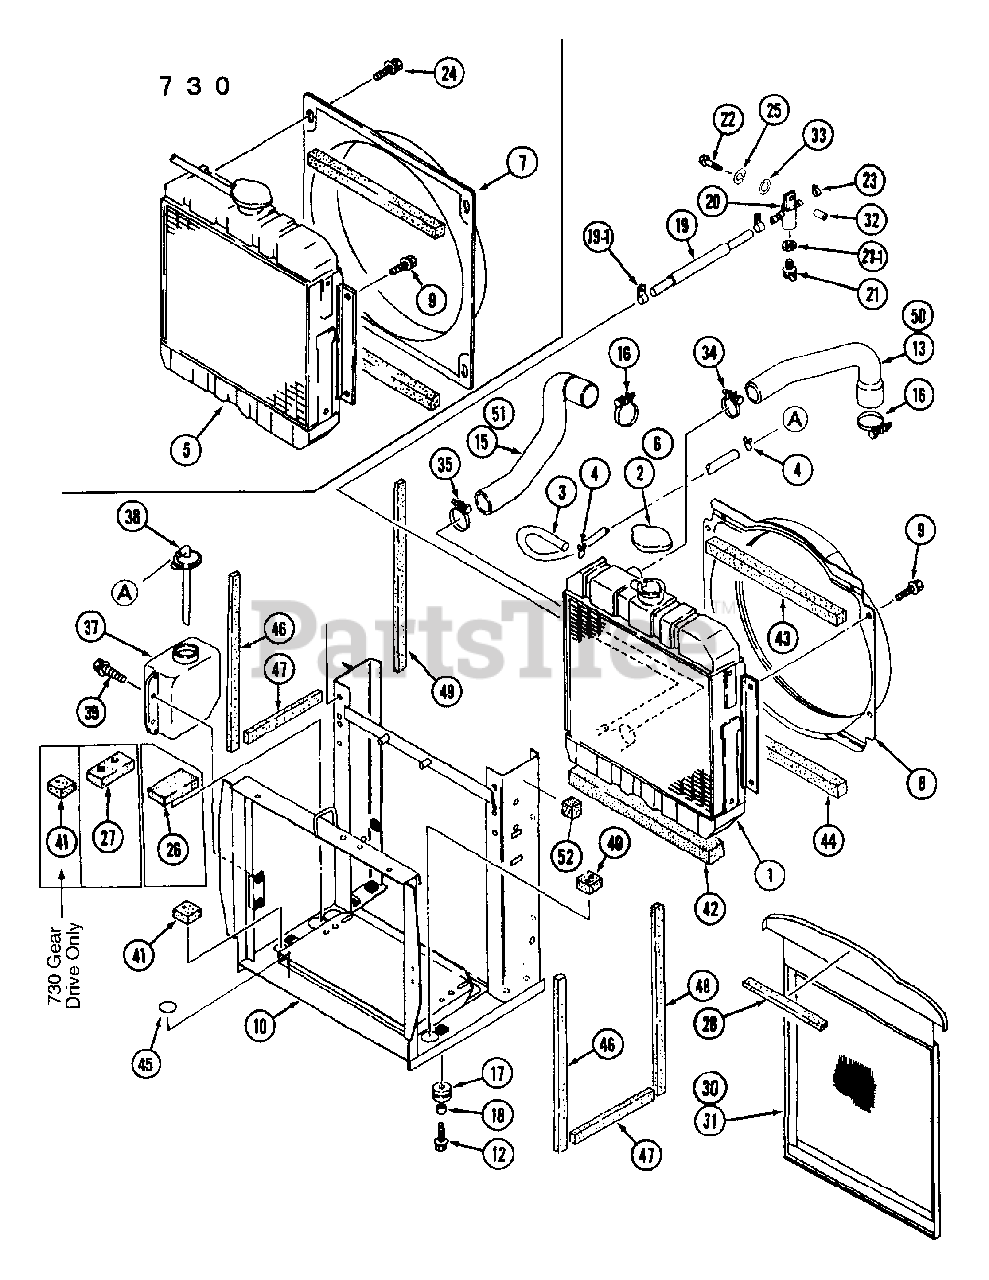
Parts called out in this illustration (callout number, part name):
1	Body, Radiator
5	Body, Radiator
6	Cap
7	Shroud, Fan
10	Bracket, Radiator
13	Hose, Upper
15	Hose, Lower
21	Cock Water
24	Bolt
25	Washer, Spring
27	Cushion
31	Net, Radiator
